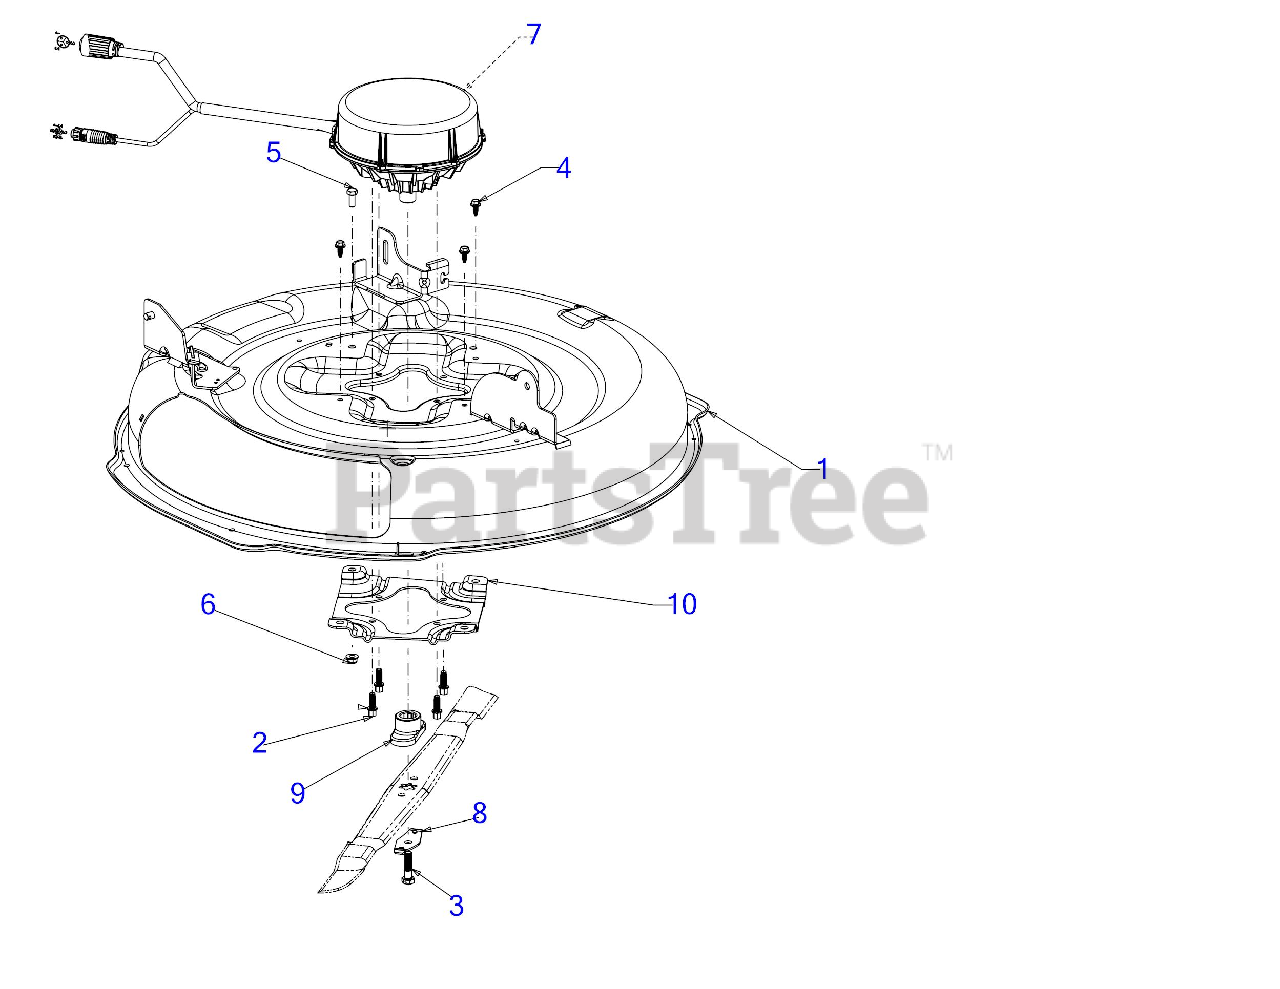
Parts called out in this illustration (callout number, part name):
2	SCREW 5/16-18 X .875
3	SCREW 3/8-24 x 1.50 GR8
4	SCREW 1/4-20X.625
5	SCREW 5/16-18 x .75 GR5
6	FLANGE LOCK NUT 5/16-18
7	30" DECK MOTOR
8	BLADE BELL SUPPORT
9	BLADE ADAPTER (#6 X 1.19 W/STAR)
